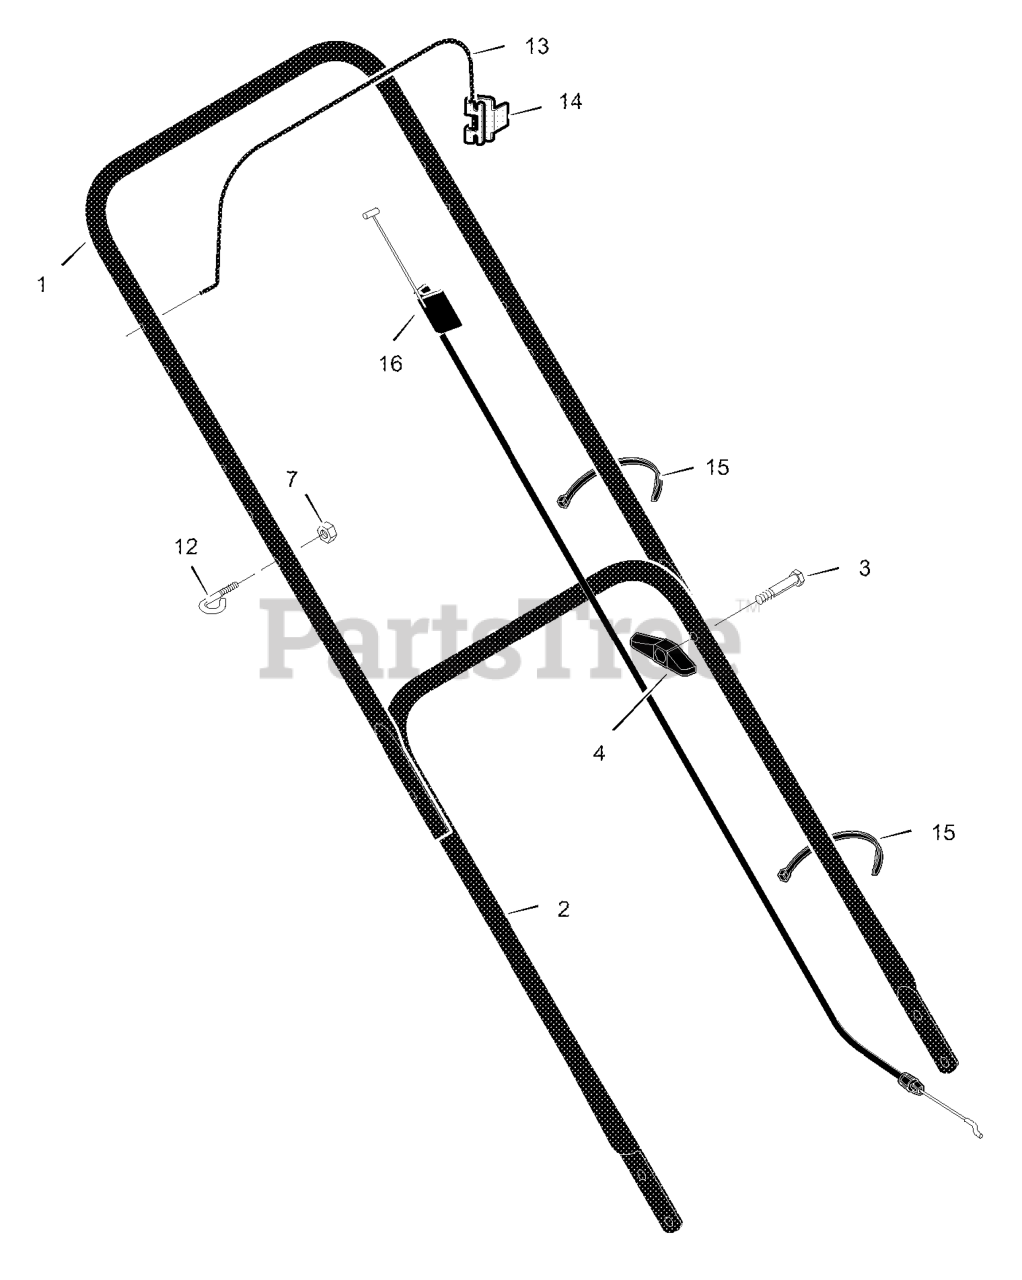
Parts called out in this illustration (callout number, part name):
1	Handle, Upper (Black)
2	Handle, Lower (Black)
4	Knob, Plastic
7	Locknut
12	Guide, Rope
13	Lever, Engine Stop
14	Bracket, Stop Lever
15	Fastener, Bable
16	Cable, Engine Stop
